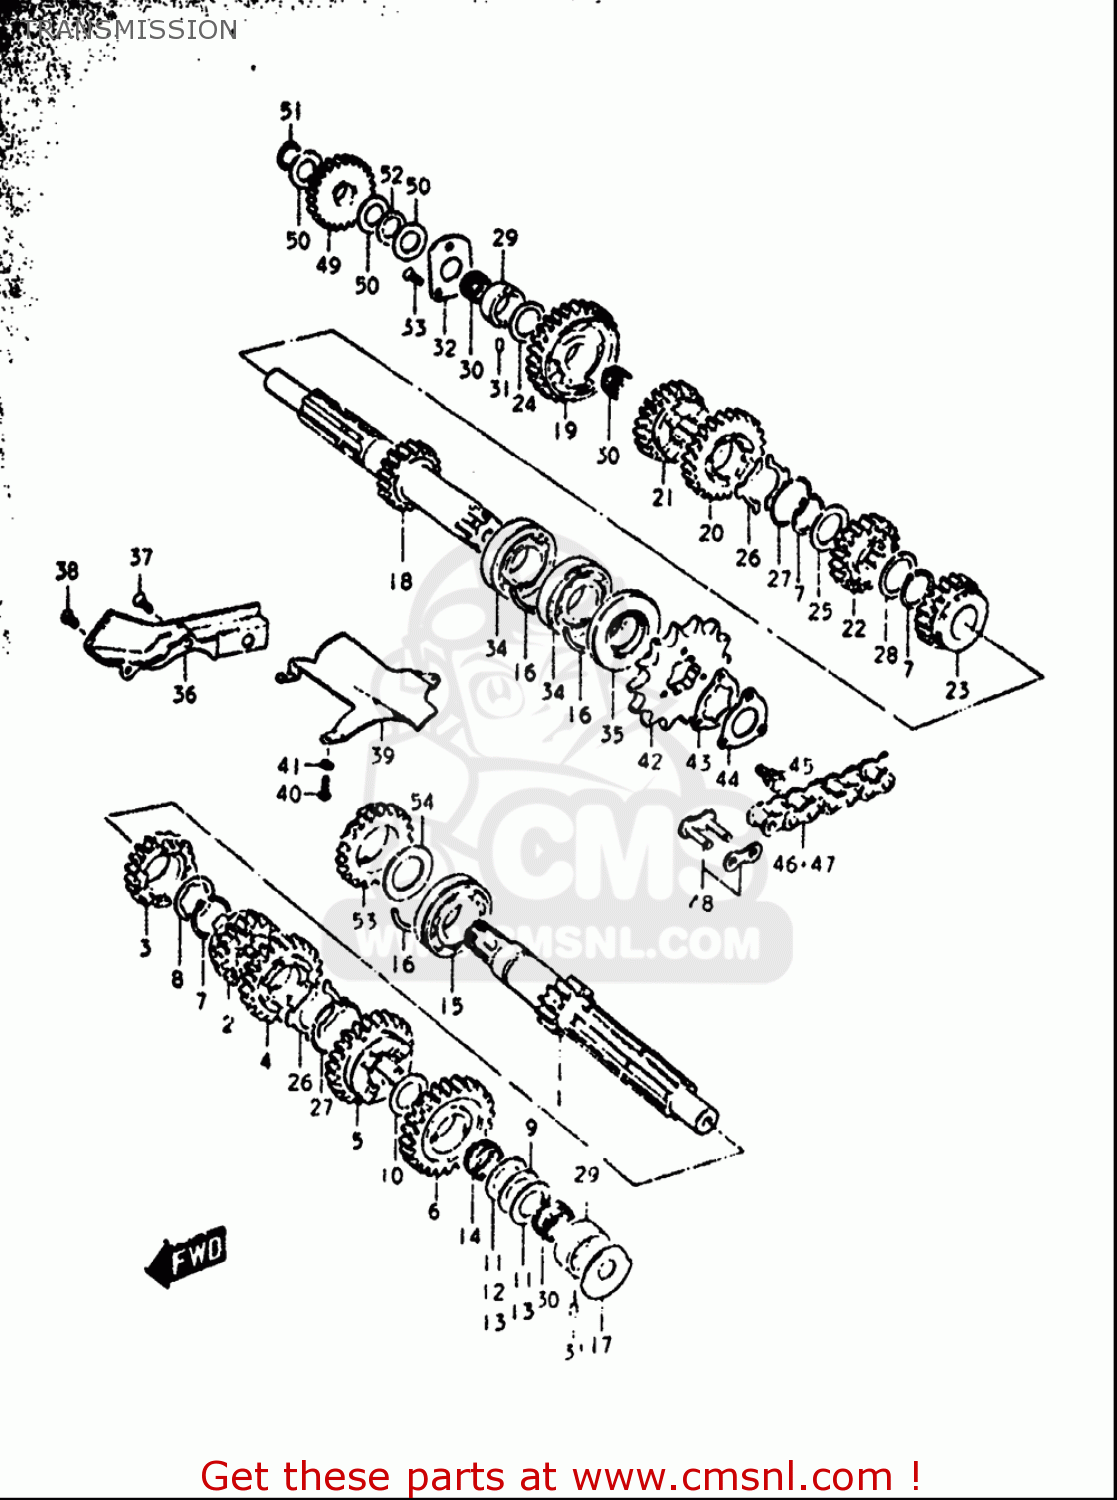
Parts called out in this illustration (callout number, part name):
7	RING,SNAP
8	WASHER
9	WASHER(17X29X1)
10	SHIM(17X30X1)
11	WASHER(21X30X1)
12	WASHER
13	WASHER
14	BEARING(17X21X9.8)
16	C RING
25	WASHER
27	CIRCLIP
28	WASHER
29	BUSHING
30	BEARING(17X21X12.8)
31	PIN
33	SCREW
34	BEARING
35	SEAL,OIL(25X52X7)
37	SCREW
38	SCREW
40	SCREW
41	WASHER,LOCK
42	SPROCKET,ENGINE
43	PLATE,ENGINE SPROCKET
44	WASHER
45	BOLT
50	SHIM(17X30X1)
51	CIRCLIP
52	WASHER
54	WASHER(25X41X3)
